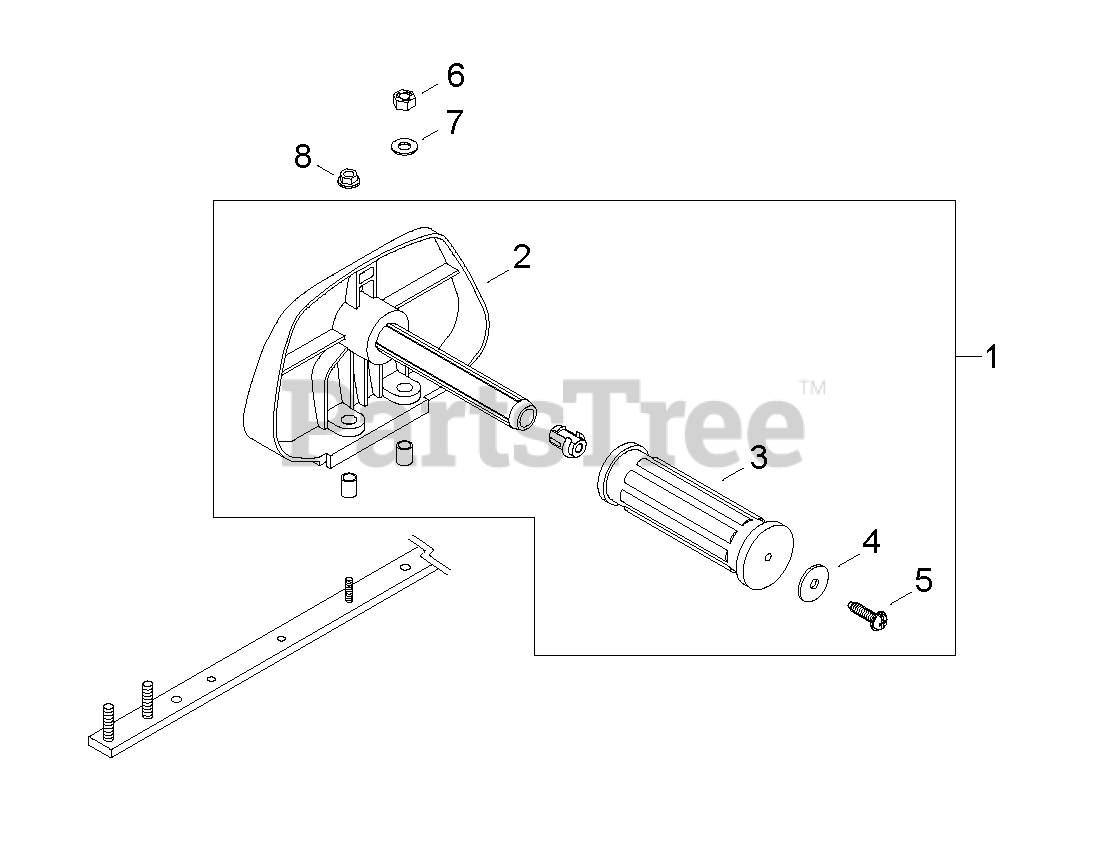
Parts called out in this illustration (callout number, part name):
1	HANDLE ASSY - FRONT
2	HANDLE - FRONT
4	WASHER - 5
5	SCREW - 5X20
6	NUT - 6
7	WASHER - 6
8	NUT - 5 -- FLANGE
